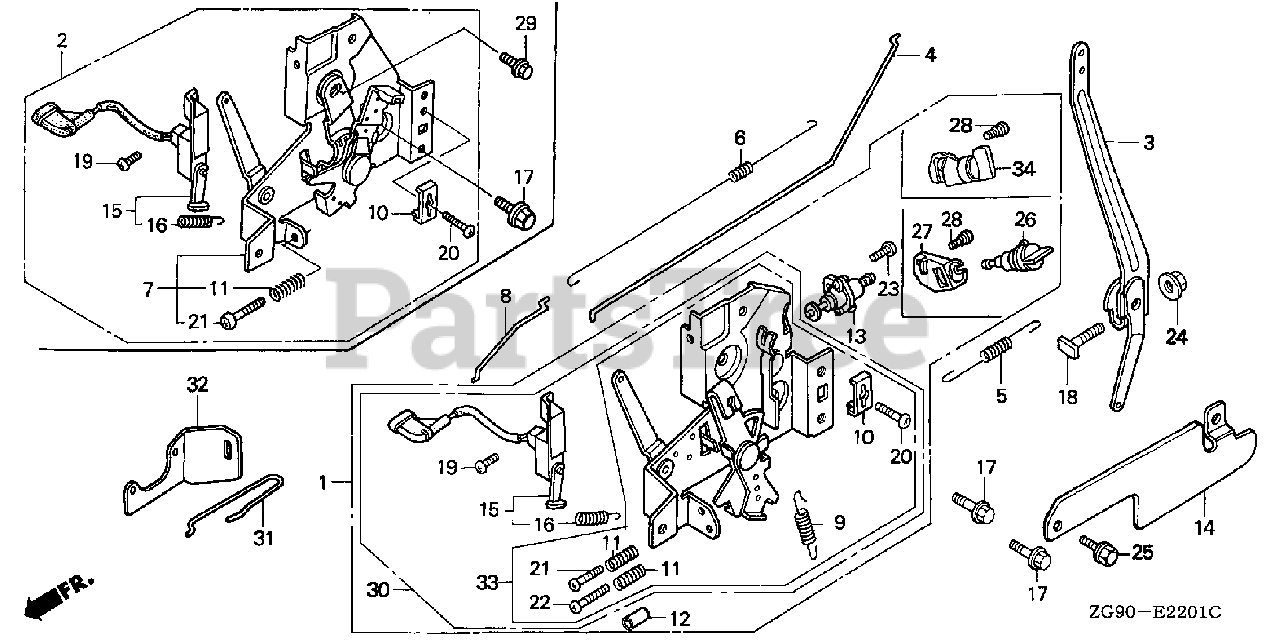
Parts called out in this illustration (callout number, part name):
1	CONTROL ASSY.
3	ARM, GOVERNOR
4	ROD, GOVERNOR
5	SPRING, GOVERNOR
6	SPRING, THROTTLE RETURN
8	ROD, CHOKE
9	SPRING, LEVER
10	HOLDER, CABLE
11	SPRING, CONTROL ADJUSTING
15	SWITCH ASSY., ENGINE STOP
16	SPRING, SWITCH CONTROL
17	BOLT, FLANGE (6X14) (CT200)
18	BOLT, GOVERNOR ARM
19	SCREW, PAN (4X8)
20	SCREW, PAN (5X16)
21	SCREW, PAN (5X20)
22	SCREW, PAN (5X25)
24	NUT, FLANGE (6MM)
26	PETCOCK ASSY.
27	BRACKET, PETCOCK
28	SCREW, SHOULDER (5X12)
